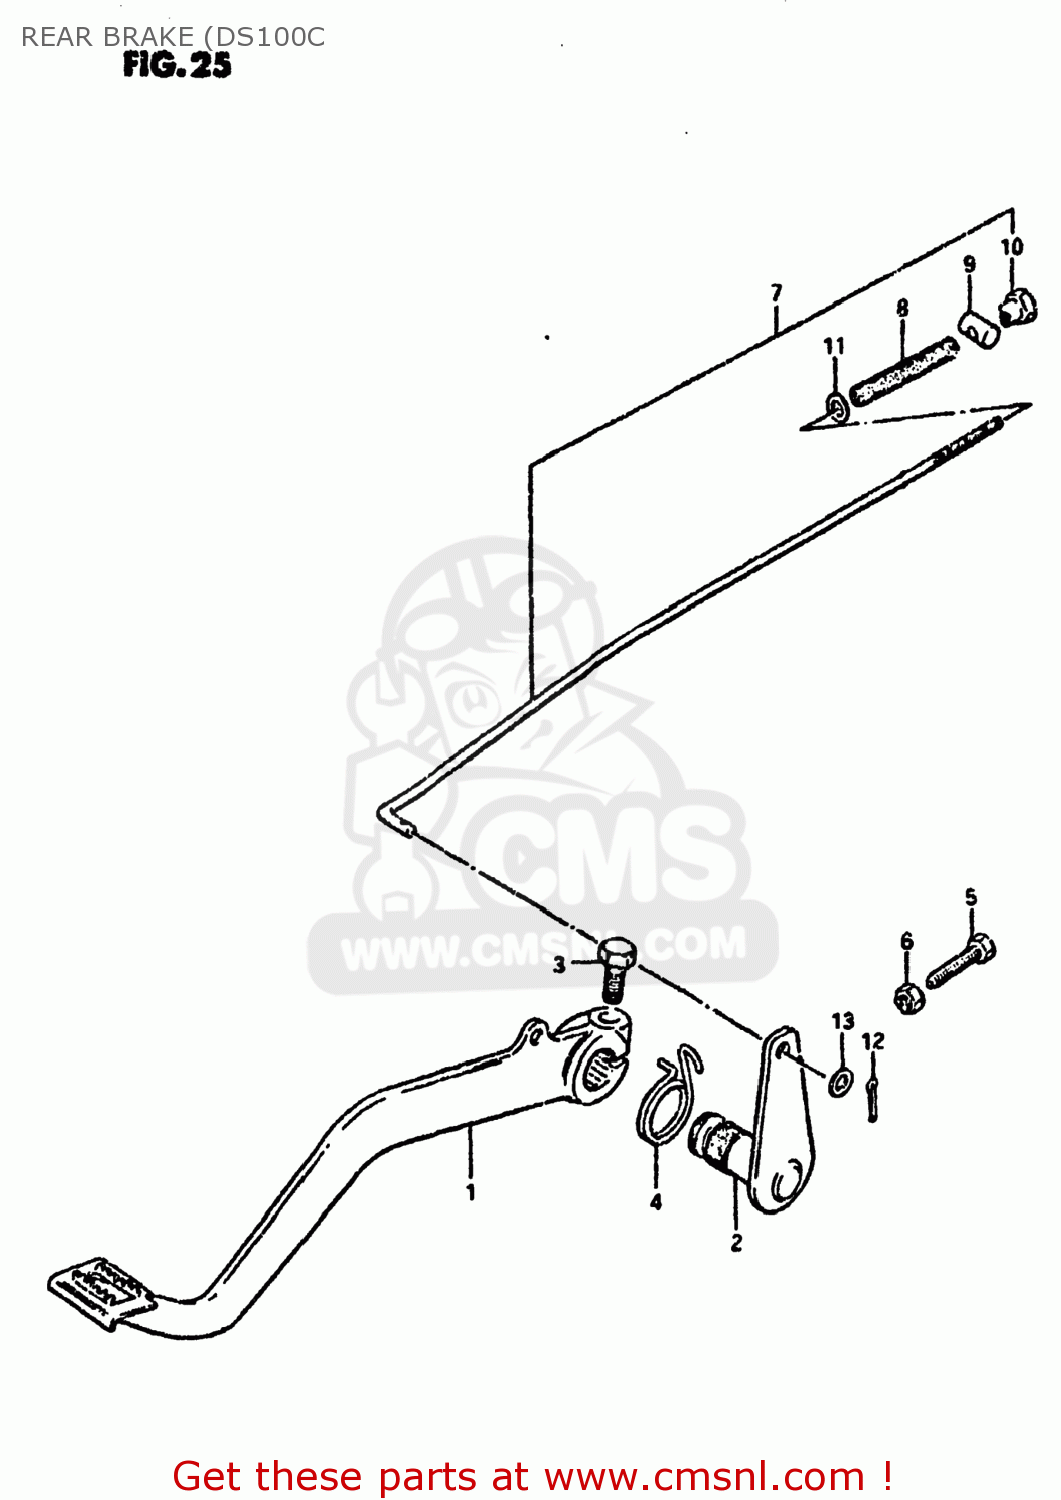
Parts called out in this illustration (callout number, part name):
1	PEDAL,BRAKE
2	ARM,BRAKE PEDAL ROD
3	BOLT
4	SPRING
5	BOLT(6X23)
6	NUT
7	ROD ASSEMBLY,REAR BRAKE
8	SPRING
9	PIN(11X18)
10	NUT
11	WASHER
12	PIN 20X20
13	WASHER
